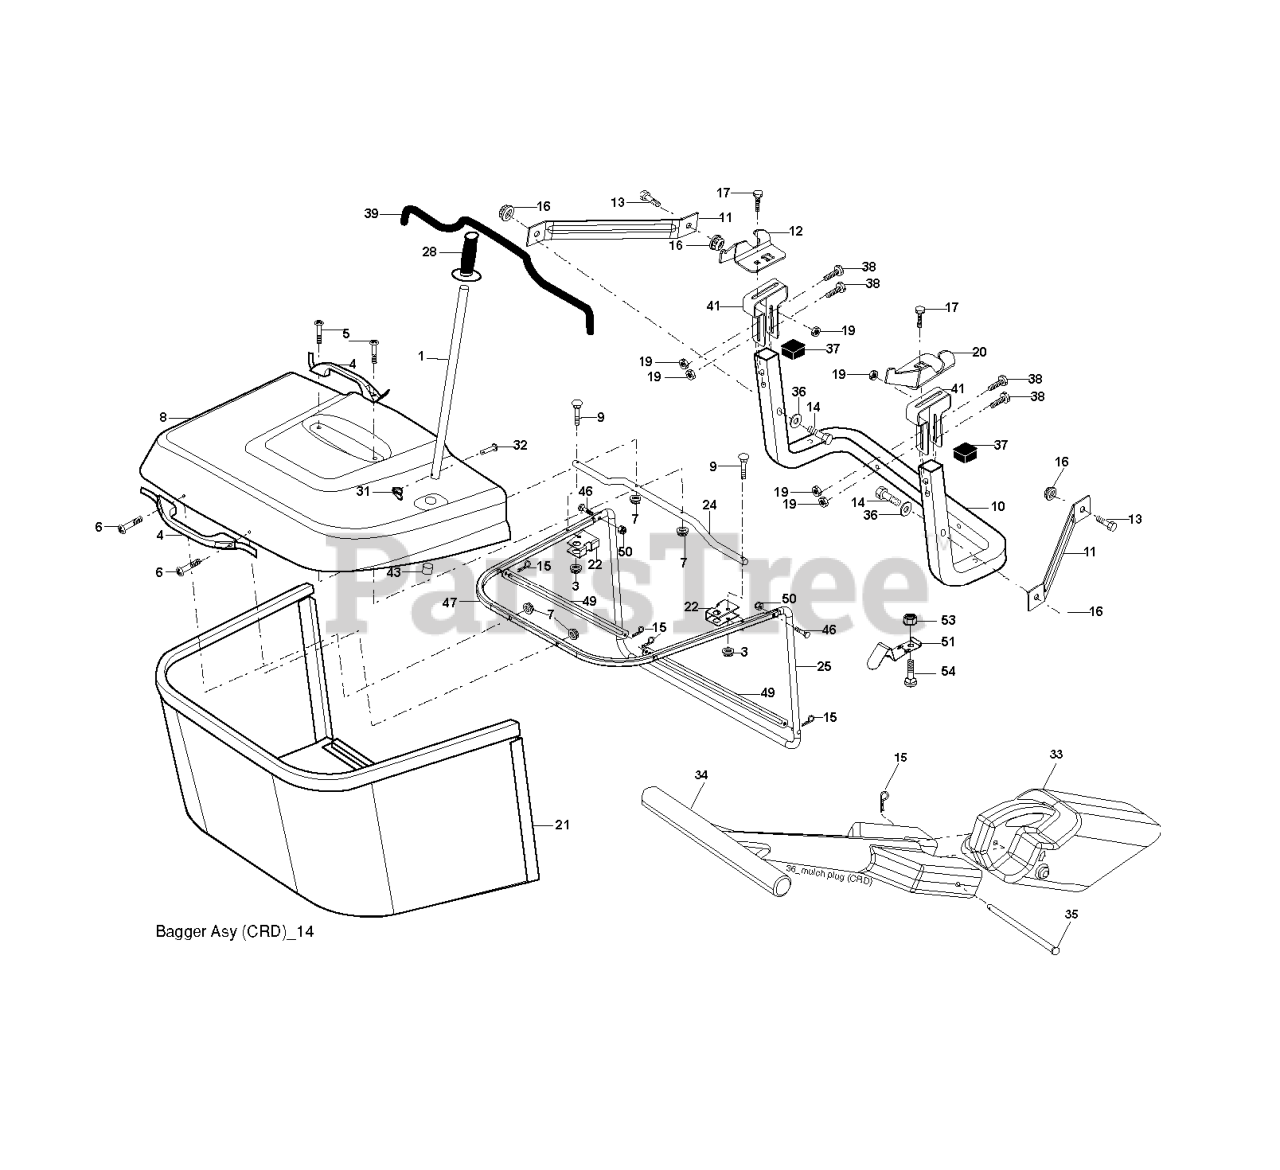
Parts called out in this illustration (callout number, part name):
1	TUBE HANDLE
3	NUT T
4	HANDLE.BAGGER.W/LVRS.BLK.CRD
5	SCREW.PAN.HEAD
6	REPL BY 532 75 00-29
8	COVER.PNT.BGR.CRD.WSLOTS.MS668
9	Bolt Carriage 1/4-20 x 2.25d x Gr.5
10	TUBE
11	BRACKET.SUPPORT.UPPER.BAG.CRD
12	BRKT PIVOT
14	BOLT-HEX EAK
15	RETAINER-SPRNG RB
16	NUT LOCK FLG 3/8-16 UNC
17	RP BOLT 5/16-18 X3/4 ZN/YEL GR
19	NUT LOCK HEX FLANGE 5/16-18
20	BRKT.PIVOT.RH.CRD
21	BAGGER.ASM.CRD.2007
22	BRKT.SIDE.BAG.CRD
24	TUBE.PIVOT.BAG.CRD.BLACK
25	PIPE
28	GRIP.HANDLE.BLACK
31	RETAINER CLIP
32	RIVET,DRILLED
33	PLUG.MULCHER.92 CRD
34	HANDLE.MULCHER.92.CRD (2 2)
36	WASHER
37	Plug Support Bagger CRD
38	BOLT.5/16-18X2.5
39	SEAL.TRIM.37'
41	BRKT.VERT.ADJ.BAGGER.CRD
43	PLUG, TUBING END
47	PIPE
49	ROD
51	LATCH
53	NUT
54	BOLT
